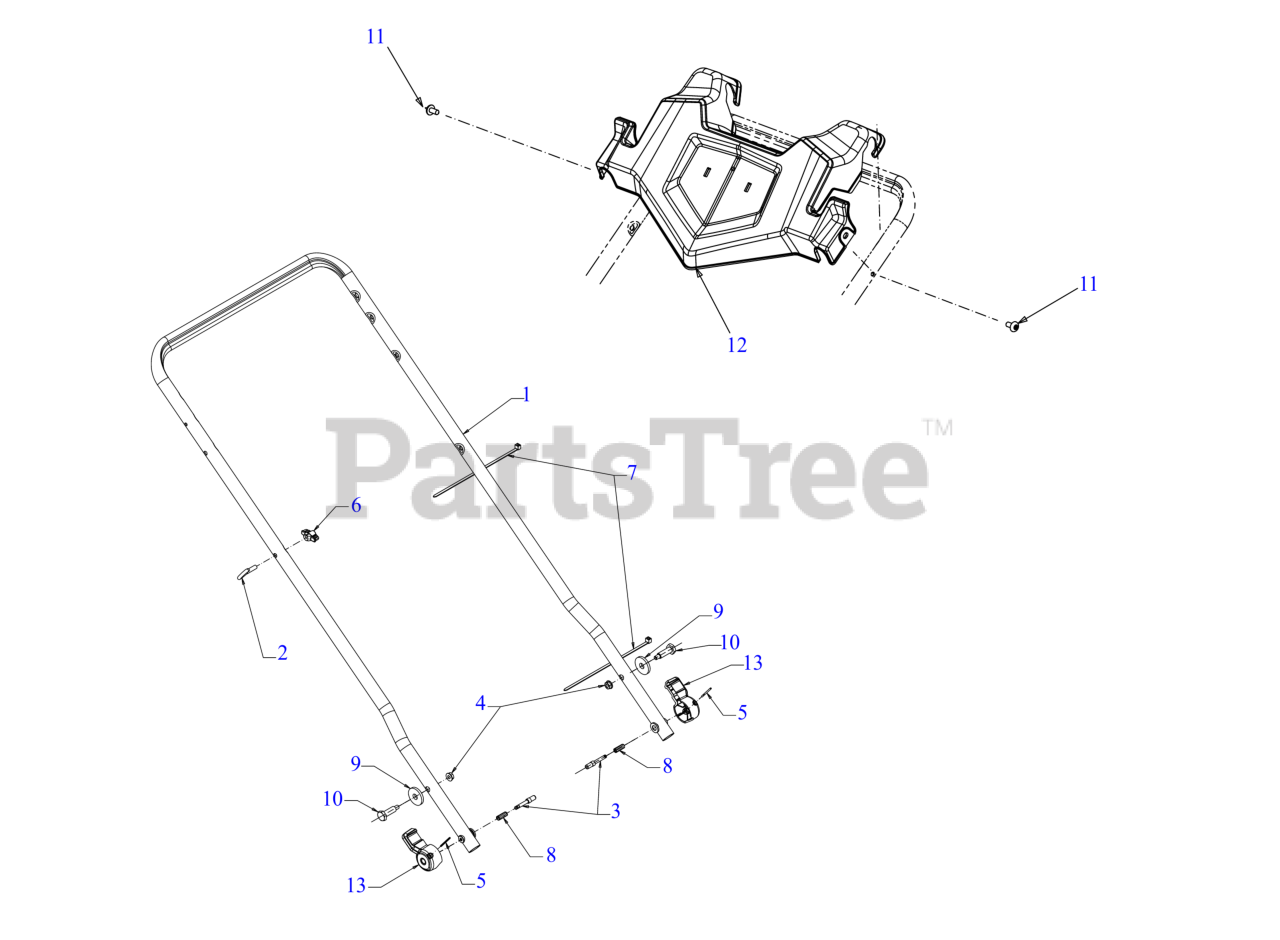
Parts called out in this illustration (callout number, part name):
1	23" HANDLE ASSEMBLY
2	EYEBOLT 1/4-20
3	HANDLE ADJUSTMENT PIN
4	LOCK NUT 1/4
5	SPLIT ROLL PIN 5/64 x 1.38
6	HANDLE KNOB
7	7" CABLE TIE
8	COMPRESSION SPRING
9	FLAT WASHER
10	SHOULDER SCREW
11	SCREW 1/4-14 x .625
12	HANDLE CONSOLE
13	LEVER HANDLE KNOB (7/8 BLACK)
